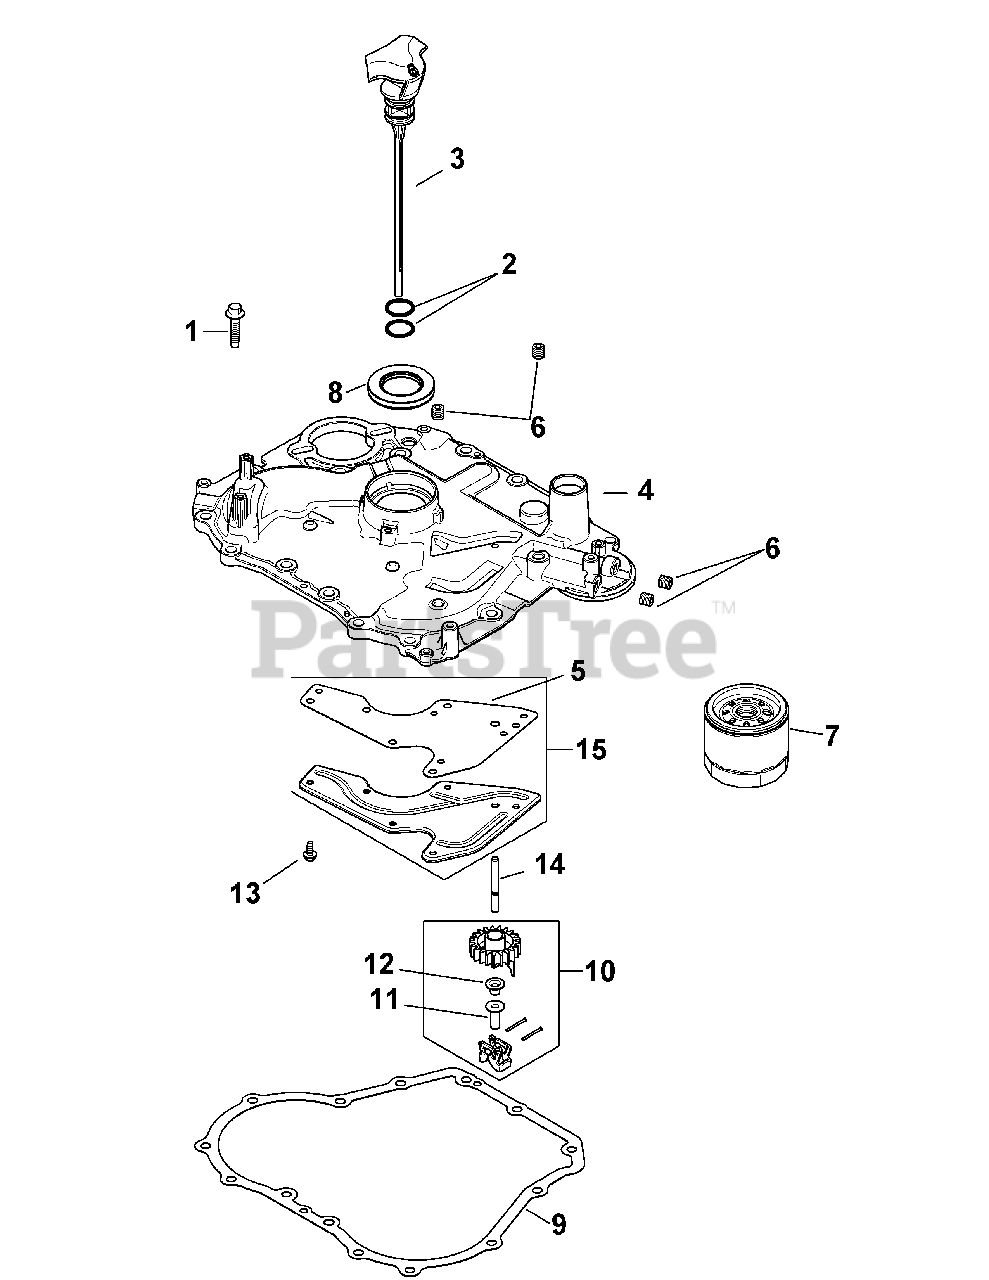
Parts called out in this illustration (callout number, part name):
1	Hex Flange Screw
3	Dipstick Ass’y-Std Yellow (Incl. 2)
4	Closure Plate Assembly
5	Oil Passage Gasket
6	Countersink Pipe Plug, 1/8
9	Closure Plate Gasket
10	Governor Gear Assembly (Incl. 11-12)
11	Governor Regulating Pin
12	Governor Regulating Pin
13	Flg. Thd. Frm. Screw, M5 X 0.8 X 13
14	Governor Cross Shaft
15	Oil Passage Cover Kit (Incl. 5)
